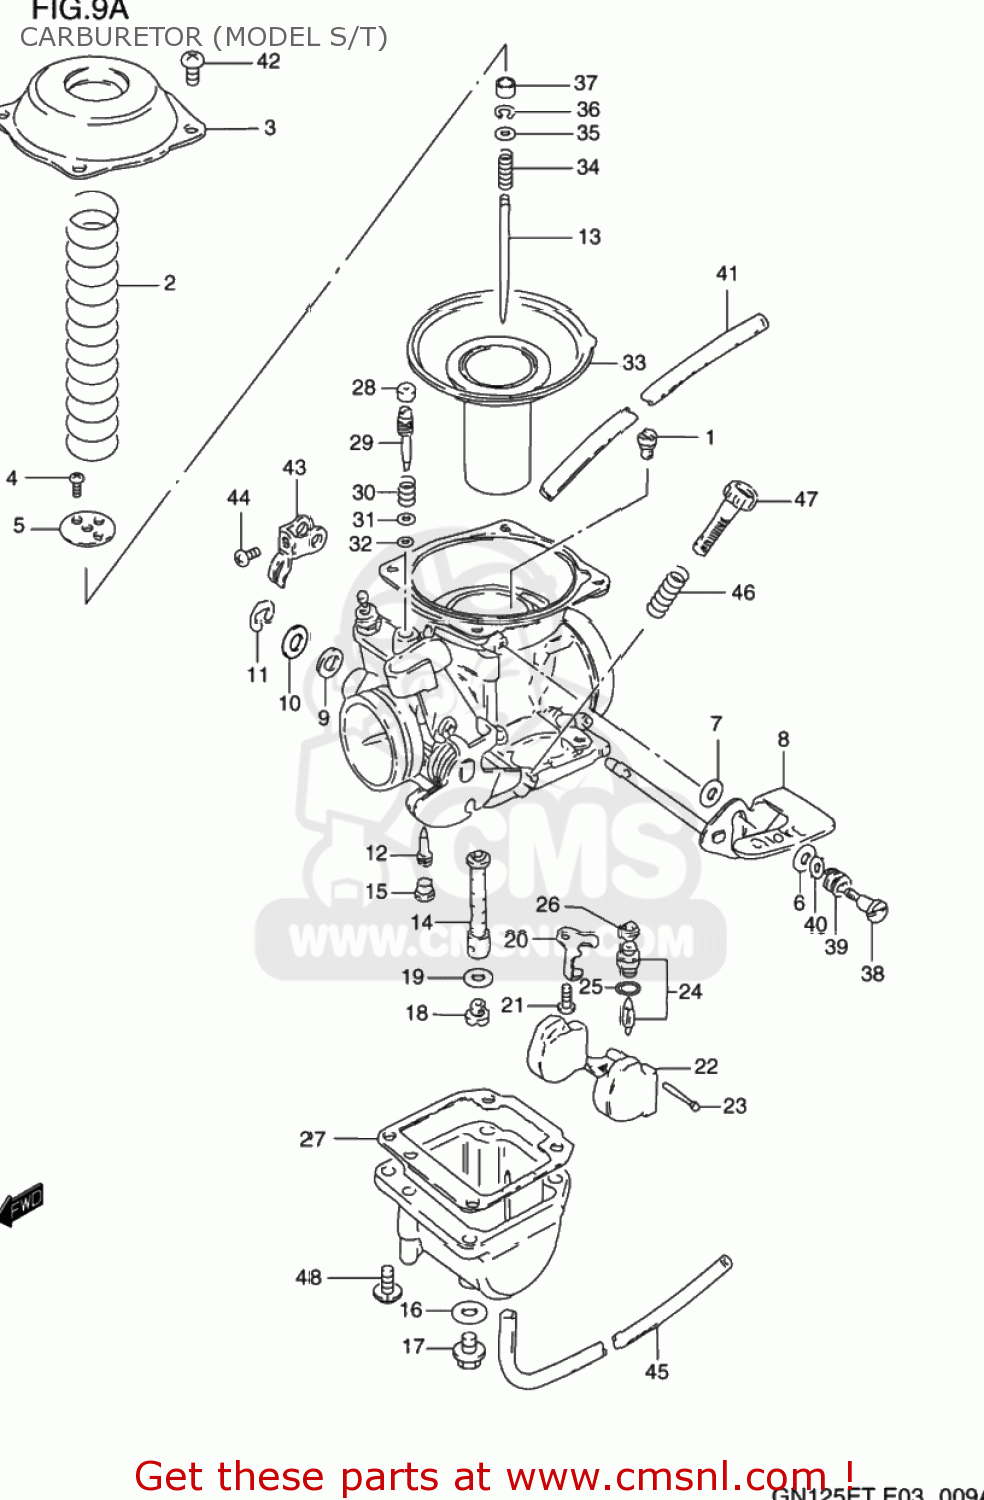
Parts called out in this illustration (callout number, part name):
1	JET,MAIN(180)
2	SPRING
3	COVER
4	SCREW
5	PLATE
6	PACKING (NAS)
7	WASHER(4.1X12X0.8)
8	SHAFT ASSY,STARTER
9	SEAL
10	GASKET,THROTTLE SHAFT (NAS)
11	E RING
12	JET,PILOT(35)
13	NEEDLE,JET
14	JET,NEEDLE(P-2)
15	PLUG,NEEDLE JET
16	GASKET (NAS)
17	PLUG,DRAIN
18	JET,MAIN(97.5)
19	WASHER,NEEDLE NOZZLE
20	PLATE
21	SCREW 4X6
22	FLOAT
23	PIN,FLOAT
24	VALVE ASSY,NEEDLE
25	O-RING,NEEDLE VALVE
26	FILTER
27	GASKET,FLOAT CHAMBER (NAS)
28	PLUG
29	SCREW,PILOT
30	SPRING
31	WASHER
32	O RING,PILOT AIR SCREW
33	DIAPHRAGM ASSEMBLY
34	SPRING
35	WASHER
36	CLIP
37	RING
38	SCREW
39	SPRING
40	WASHER,STARTER SHAFT
41	HOSE(5X8.2X600)
42	SCREW
43	LEVER
44	SCREW
45	HOSE(3.6X6X600)
46	SPRING,THROTTLE SCREW
47	SCREW,THROTTLE STOP
48	SCREW
